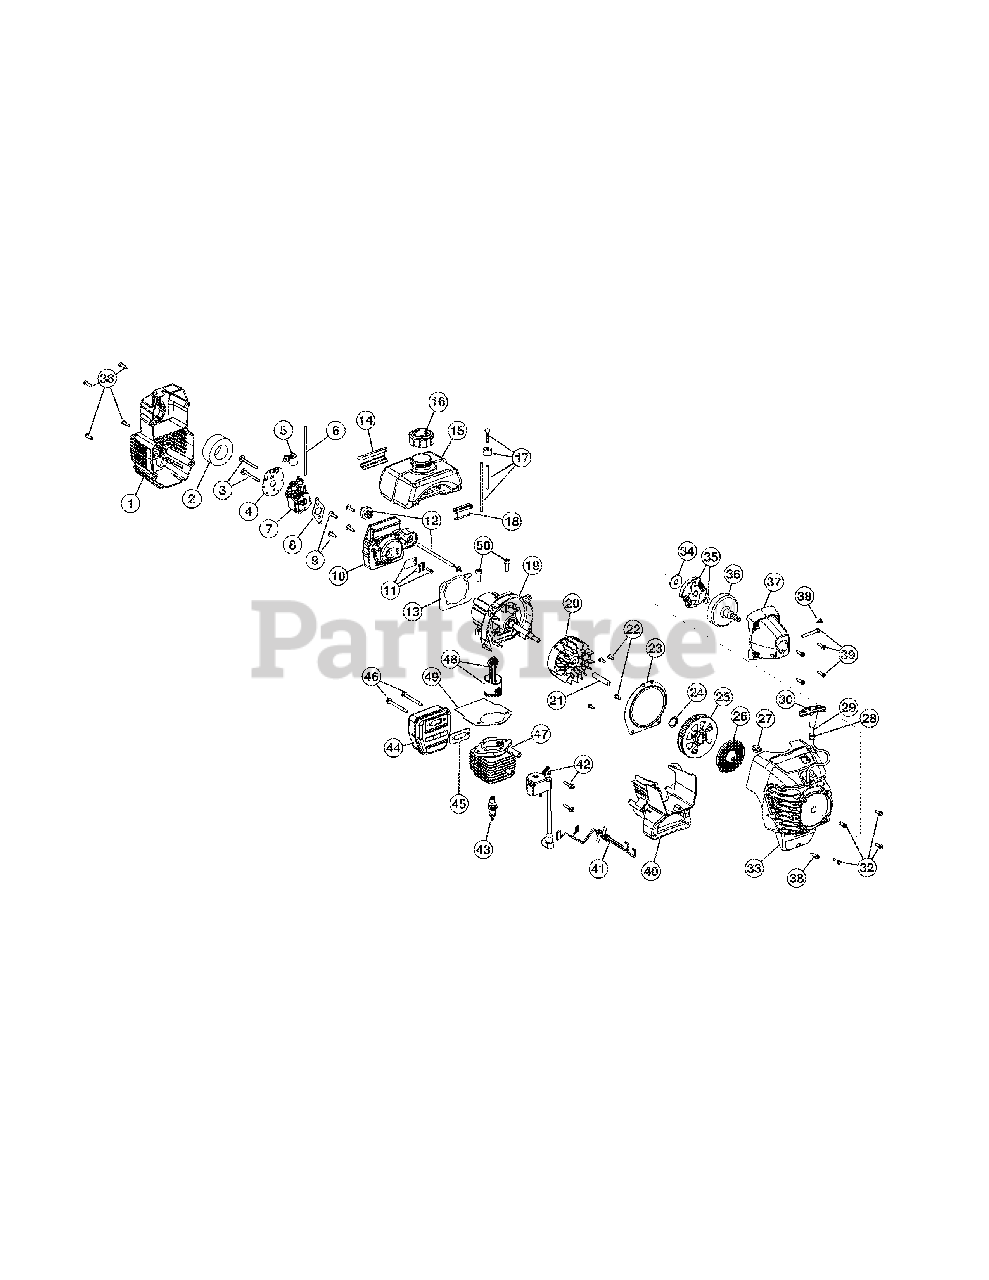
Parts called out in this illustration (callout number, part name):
1	Air Cleaner Cover Assembly (includes 2 & 38)
2	Air Cleaner Filter
3	Carburetor Mounting Screw Assembly
4	Choke Plate
5	Choke Lever
6	Fuel Return Line
7	Carburetor Assembly (includes 8 & 17)
8	Carburetor Gasket
9	Carb Mount Screw
10	Carb Mount Assembly (includes 9, 11 & 13)
11	Reed Assembly
12	Primer and Hose Assembly
13	Carburetor Mount Gasket
14	Rear Mounting Pad
15	Fuel Tank Assembly (includes 6,16 & 17)
16	Fuel Cap Assembly
17	Fuel Line Assembly
18	Front Mounting Pad
19	Crank Case Service Assembly (includes 9)
20	Flywheel Assembly
22	Pressure Plate Screw
23	Pressure Plate
24	Pulley Retainer
25	Recoil Pulley Assembly
26	Recoil Spring
27	Rope Guide Retainer
28	Rope Guide
30	Pull Handle
32	Housing Screw
33	Starter Housing Assembly (includes 22-30, 32 & 38)
34	Clutch Washer
35	Clutch Rotor Assembly
36	Clutch Drum Assembly
37	Clutch Cover Assembly (includes 38 & 39)
38	Anti-Rotation Screw
39	Cover Screw
40	Shroud Extension & Stand (includes 38)
41	Wire Leads and Sleeve
42	Module Assembly
43	Spark Plug
44	Muffler Assembly (includes 45 & 46)
45	Exhaust Gasket
46	Muffler Mounting Bolt Assembly
47	Cylinder Assembly (includes 49 & 50)
48	Piston and Rod Assembly
49	Cylinder Gasket
50	Cylinder Bolt
